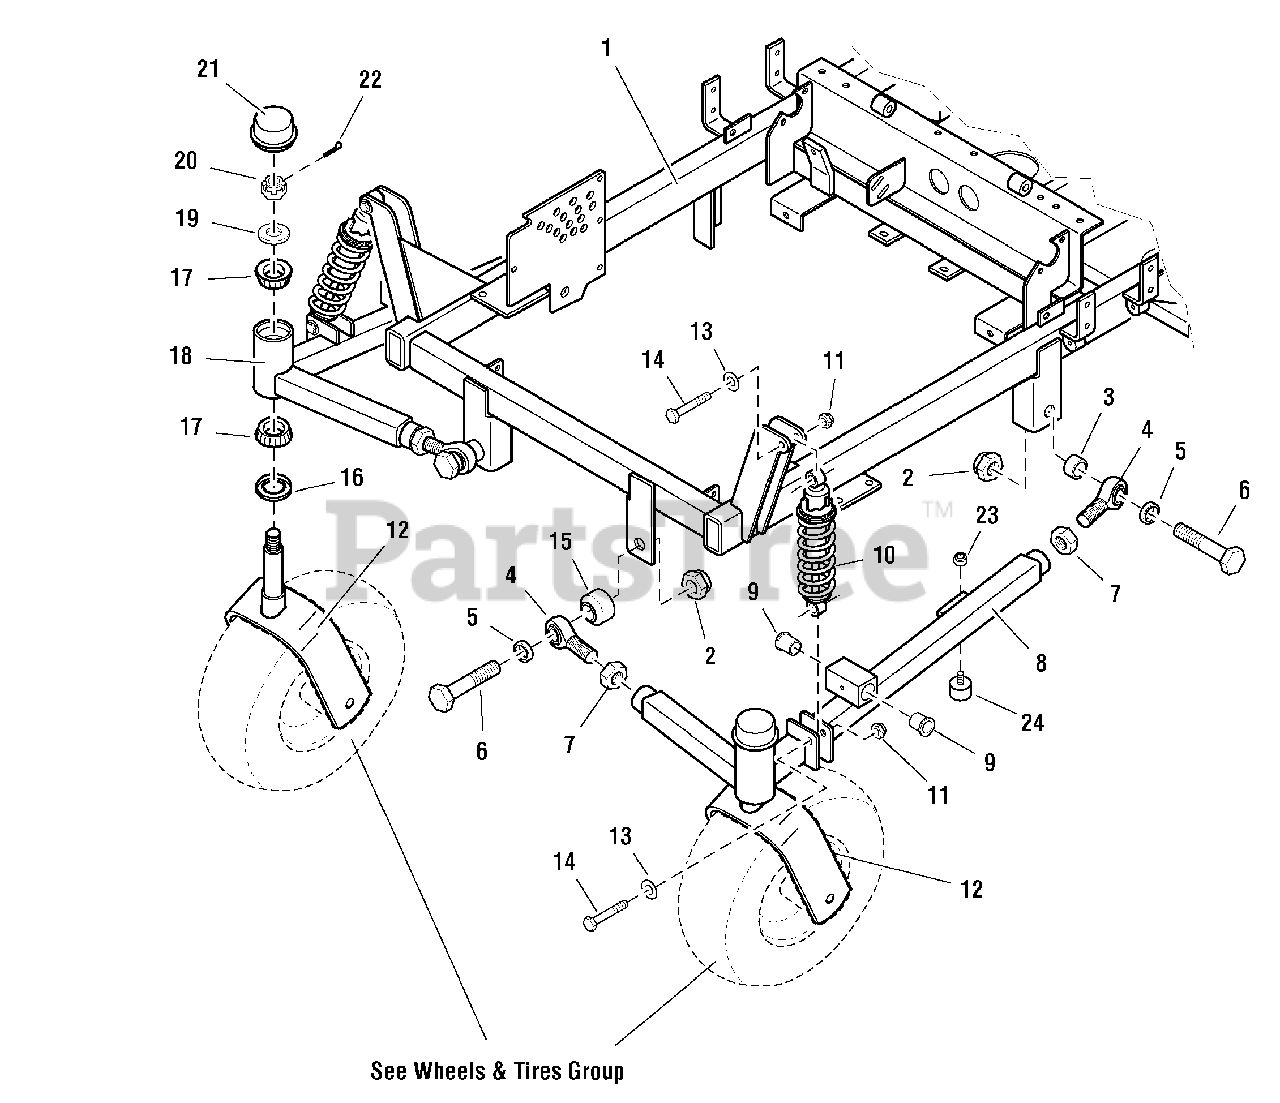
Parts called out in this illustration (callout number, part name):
2	NUT, 3/4-16 Hex Nylon Lock
3	SPACER, .76 x 1.00 x .50
4	BALL JOINT, 3/4-16 Male
5	SPACER, .76 x 1.00 x .25
6	BOLT, 3/4-16 x 3-1/2
7	NUT, 3/4-16 Hex Jam
8	SUSPENSION ARM ASSEMBLY - LH
9	BUSHING, Flange
10	SHOCK & SPRING ASSEMBLY
11	NUT, 3/8-16 Hex Nylon Lock
12	CASTER TIRE MOUNT
13	WASHER, 3/8" SAE
14	BOLT, 3/8-16 x 2-1/4
15	SPACER, .75 x 1.50 x 1.00
16	GREASE SEAL
17	BEARING, Tapered Roller
18	SUSPENSION ARM ASSEMBLY - RH
19	WASHER, 3/4" SAE
20	NUT, 3/4-16 Hex Slotted
22	COTTER PIN, 1/8" X 1-1/4"
23	NUT, 1/4-20 Hex Nylon Lock
24	RUBBER BUMPER
